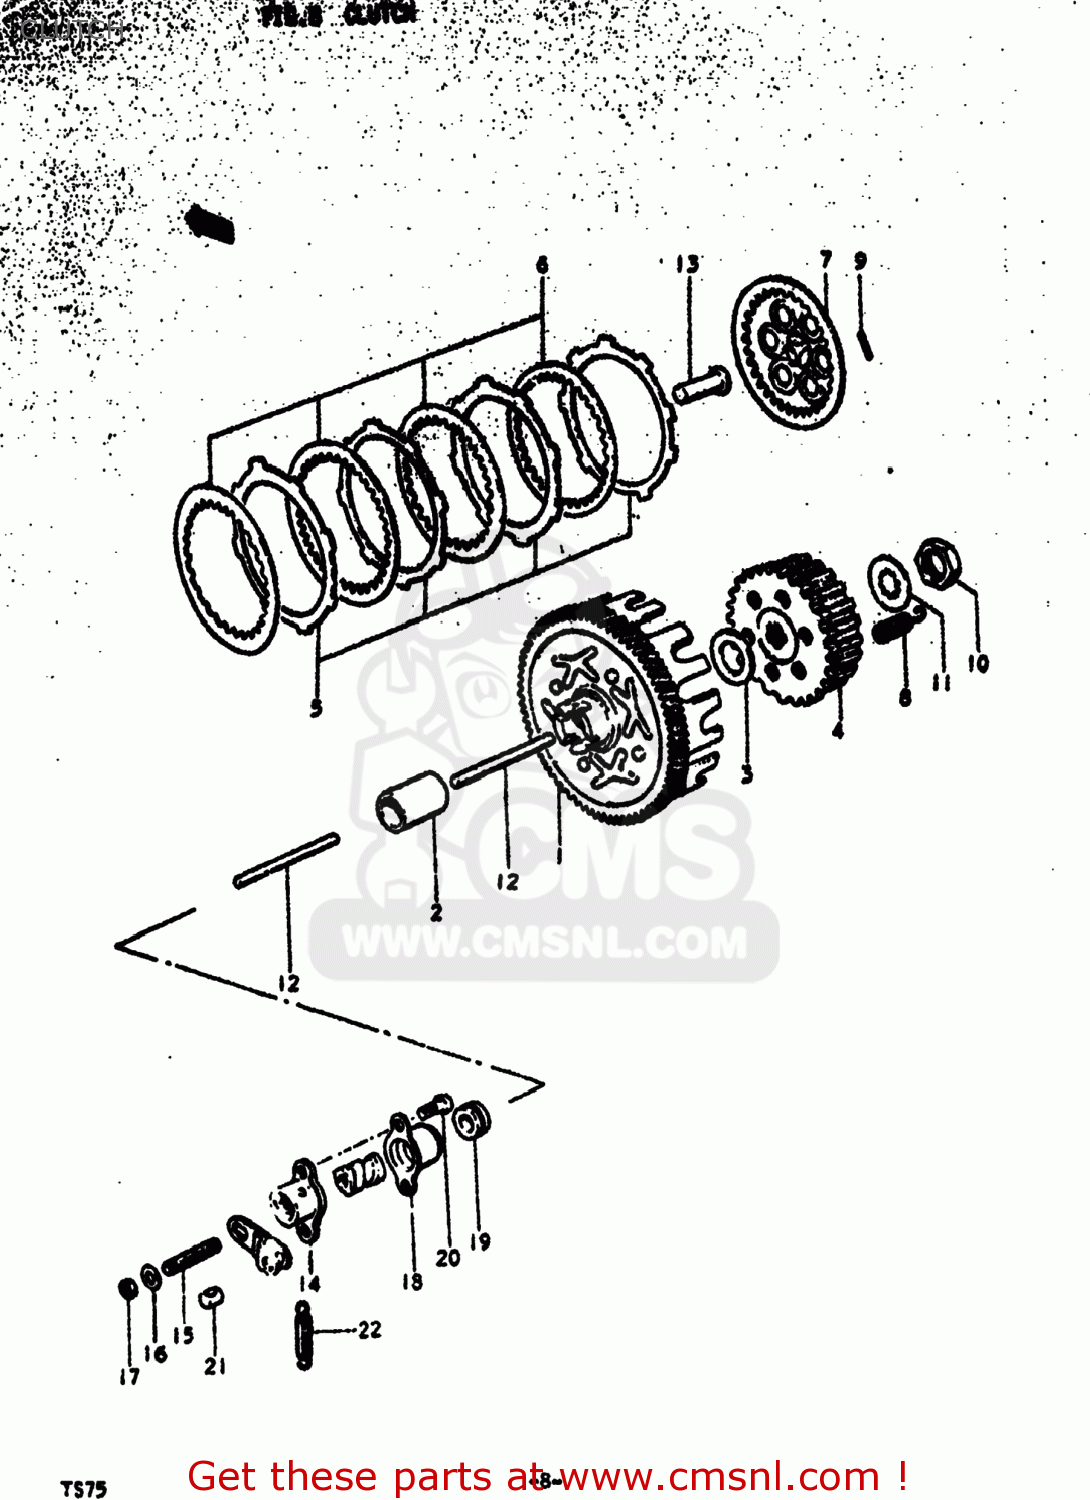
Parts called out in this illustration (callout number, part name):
1	GEAR ASSEMBLY,PRIMARY DRIVE
2	SPACER (17X21X52)
3	WASHER
4	HUB,CLUTCH SLEEVE
5	PLATE,CLUTCH DRIVE (MCA)
6	PLATE,CLUTCH DRIVEN (NAS)
7	PLATE,CLUTCH PRESSURE
8	SPRING
9	PIN(2.5X19.8)
10	NUT
11	WASHER,LOCK
12	ROD,CLUTCH PUSH
13	PIECE,CLUTCH PUSH
14	SCREW ASSEMBLY,CLUTCH RELEASE
15	SCREW
16	WASHER(6.5X16X1.2)
17	NUT
18	COVER,CLUTCH RELEASE SCREW
19	SEAL,DUST(5.3X13X5)
20	SCREW
21	PIECE,RELEASE ARM END
22	SPRING
